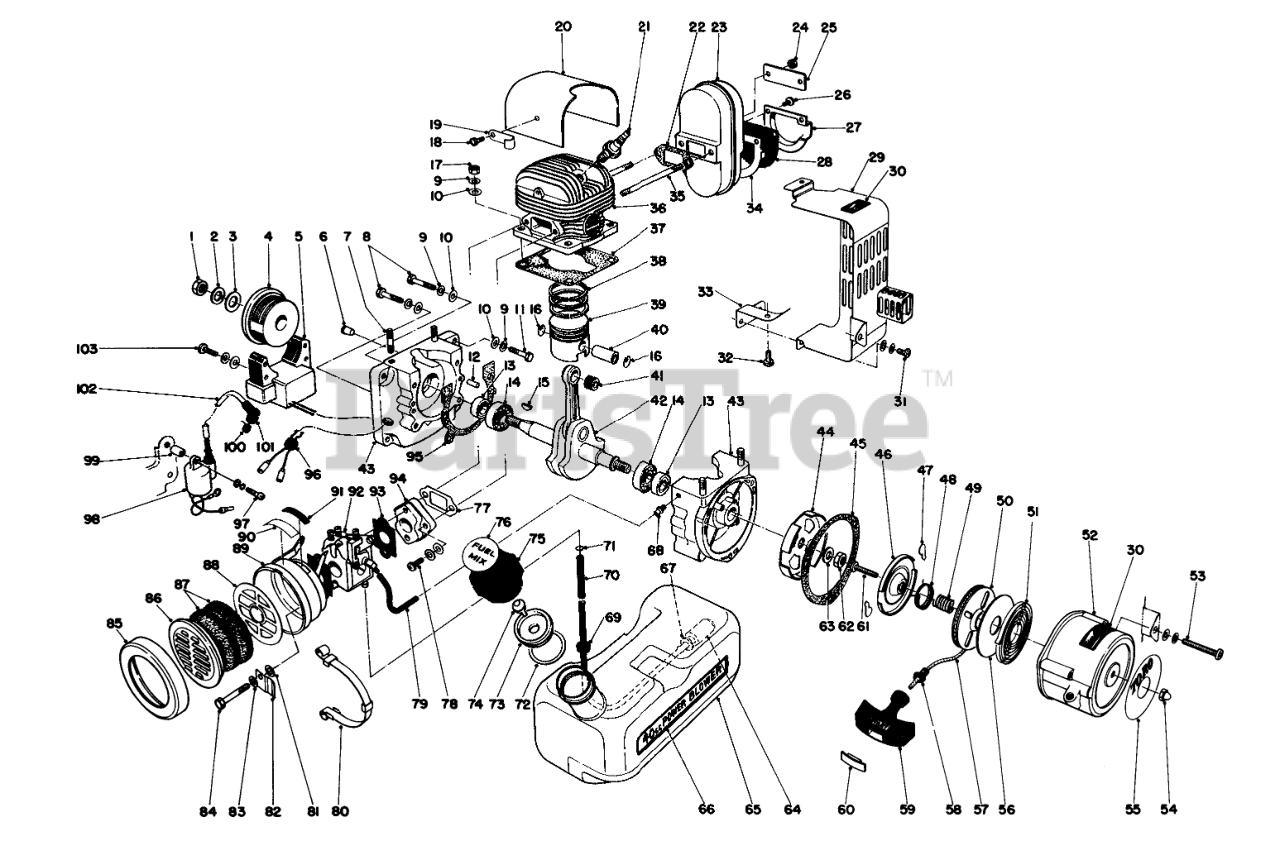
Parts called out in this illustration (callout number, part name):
2	Spring Washer
3	Washer
4	Rotor
5	C.D.I. MODULE - ECHO
7	Stud Bolt
9	Washer
10	Washer
12	Knockpin
13	Oil Seal
14	Ball Bearing
15	Woodruff Key
16	CIRCLIP PISTON PIN
19	Clamp
20	Cylinder Cover
21	Spark Plug
22	Gasket Muffler
23	Muffler
24	Locknut
25	Washer
26	SCREW
27	Muffler Lid
28	Screen
29	MUFFLER COVER
30	Decal-Hot Surface
31	Screw
32	Screw
33	Supporter
34	Seat Screen
35	STUD BOLT
36	Cylinder
37	Packing Cylinder Base
38	PISTON RING
39	Piston
40	Piston Pin
41	Needle Bearing
42	Crankshaft Assembly
43	Crankcase Set
44	PAWL CATCHER
45	STARTER CASE GASKET
46	FRICTION PLT
47	RATCHET
48	RATCHET SPRING
49	SPRING
50	Recoil Drum
51	REWIND SPRING
52	Starter Case
53	SCREW
54	Cap Nut
55	Decal-Toro
56	Side Plate, Starter
57	Starter Rope
58	Rope Guide
59	Starter Handle
60	Cap, Starter Handle
61	Screw
63	Washer
64	Fuel Strainer
65	Fuel Tank
66	Decal-40cc
67	Washer
68	Connector
69	GROMMET
70	FUEL PIPE
71	Clip Fuel Pipe
72	FUEL TANK GASKET
73	Holder, Check Valve
74	Check Valve
75	FUEL TANK CAP - WILLMAR
76	Decal-Fuel Mix
77	GASKET
78	SCREW
80	COVER HOLDER
81	Washer
82	Choke Clip
83	Washer
85	AIR CLEAN COVER HLDR
86	AIR CLEANER COVER
87	Air Filter
89	CLEANER CASE-WILLMAR
90	Decal-Caution
92	CARBURATOR ASM
93	GASKET
94	INSULATOR
95	Packing, Crankcase
96	Grommet
97	Screw
98	IGNITION COIL
99	Spacer
100	Coil Spring-Plug Cap
101	Cap-Spark Plug
102	Sleeve
